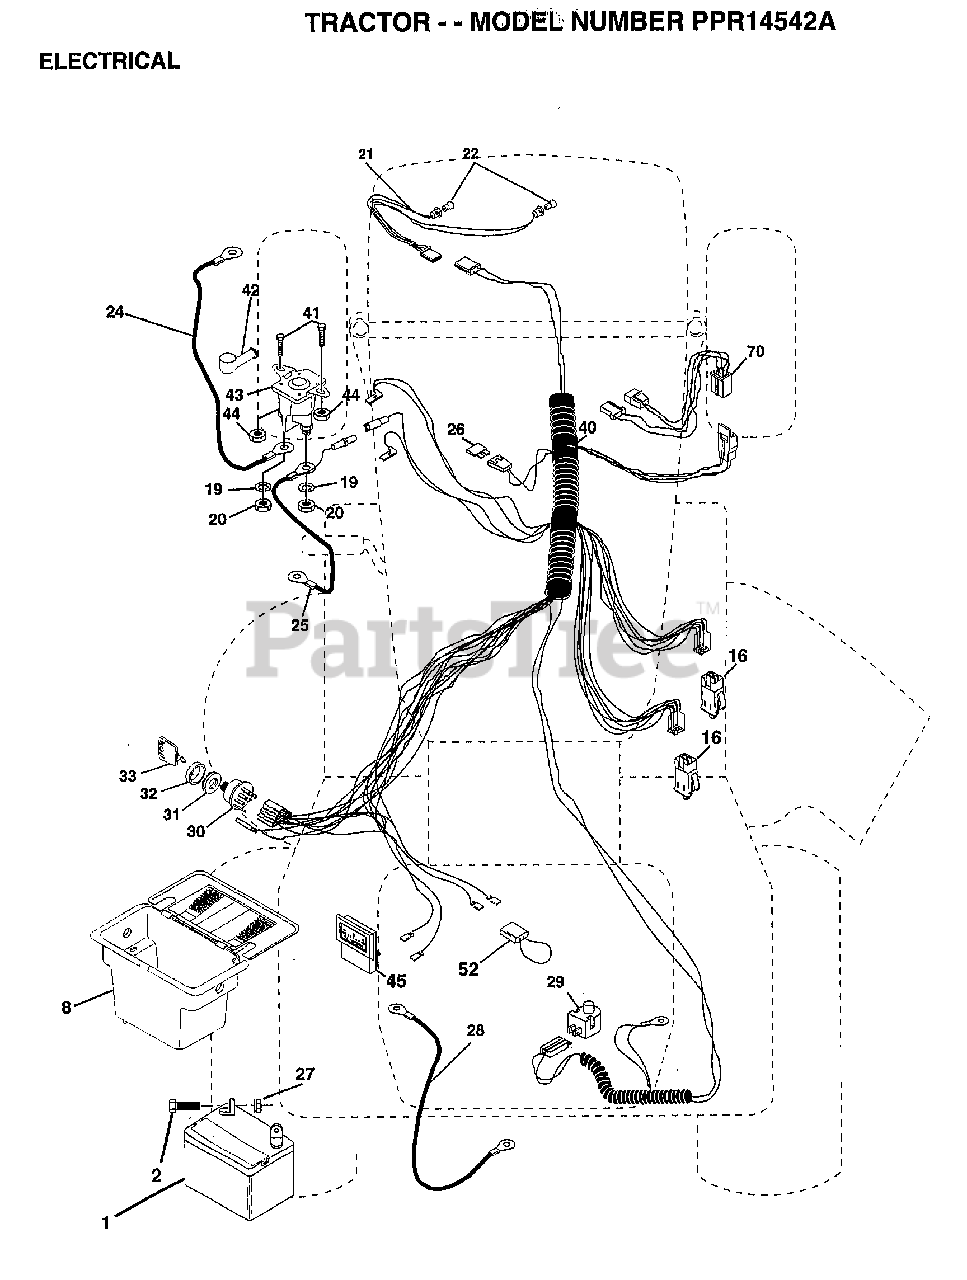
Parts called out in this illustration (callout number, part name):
2	BOLT LT
8	"CASE,BATTERY.MECH"
16	SWITCH INTERLOCK
21	HARNESS.ASM.LIGHT W/4152J
22	HEADLAMP BULB
24	"CABLE T, BATTERY"
25	CABLE.BTRY.6GA.RD
26	FUSE.15 AMP
27	NUT
28	CABLE T
29	SWITCH SEAT
30	SWITCH IGN 4POS
31	NUT IGNITION
32	COVER KEY SWITCH
33	KEY
40	HARNESS.IGNITION
41	BOLT HXHD FIN
44	NUT HXKEP 1/4X20
52	PROTECTION LOOP
70	HARNESS.ENGINE.B&S
